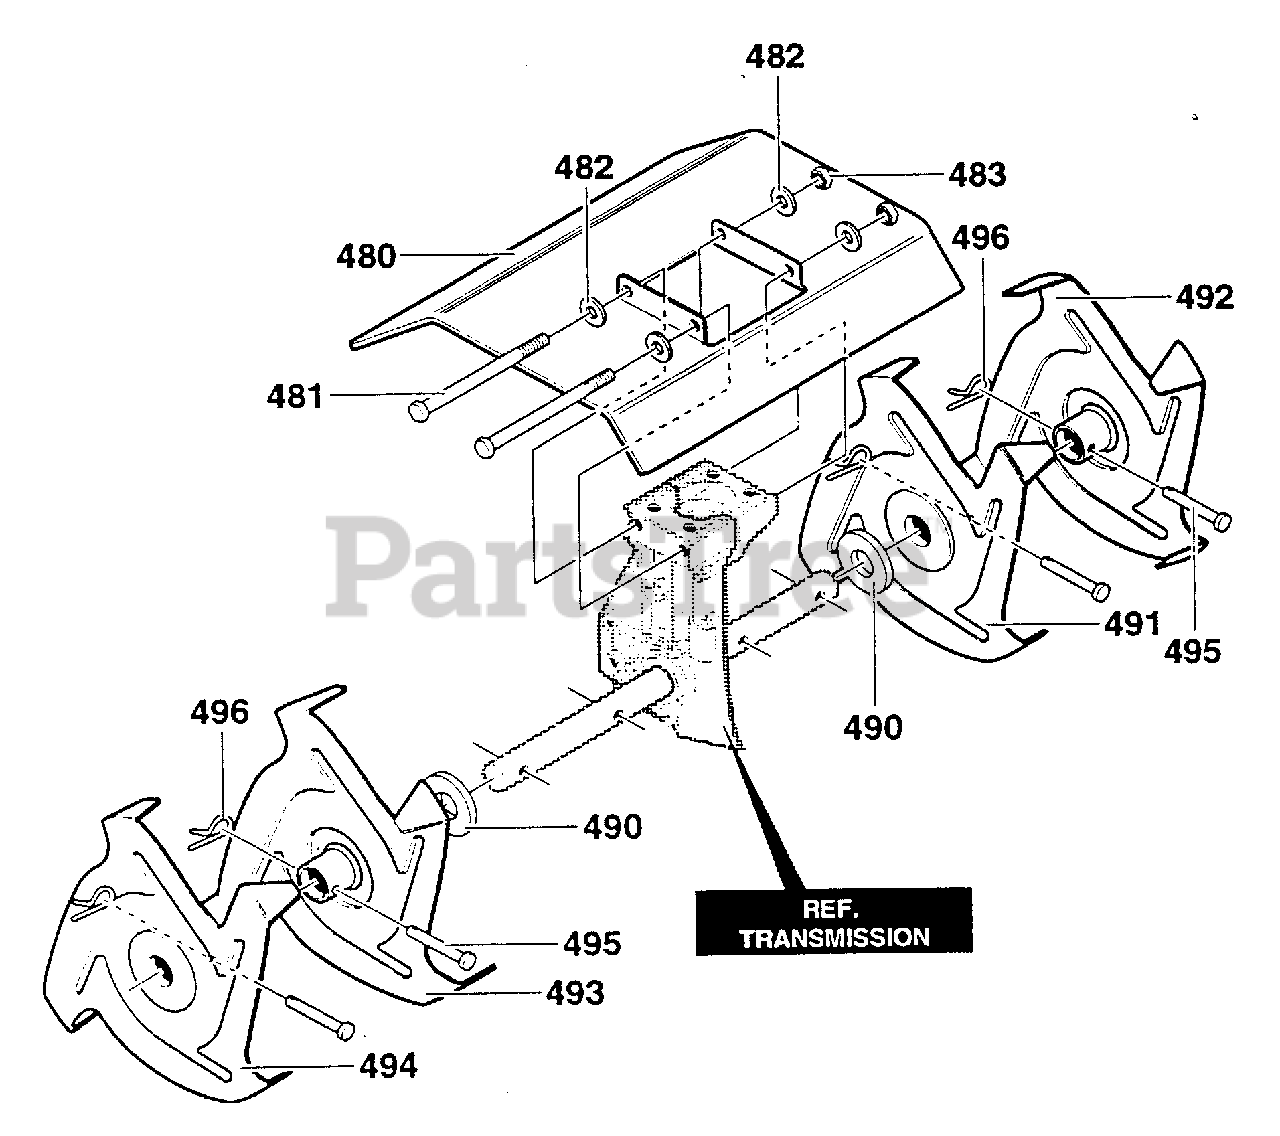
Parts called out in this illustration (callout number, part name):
480	SHIELD, TINE
481	SCREW, 1/4-20 X 5.00 HHC
482	WASHER, FLAT .281 X .63 X.065
483	NUT, 1/4-20 REGHEXCTRLK
490	WASHER, FELT.68 X 1.46 X.12 WOOL
491	TINE, ASSY INNER LH
492	TINE, ASSY OUTER LH
493	TINE, ASSY INNER RH
494	TINE, ASSY OUTER RH
495	PIN, CLEVIS .31 X 1.38
496	PIN, HAIR .53 DIA X 1.62LG
